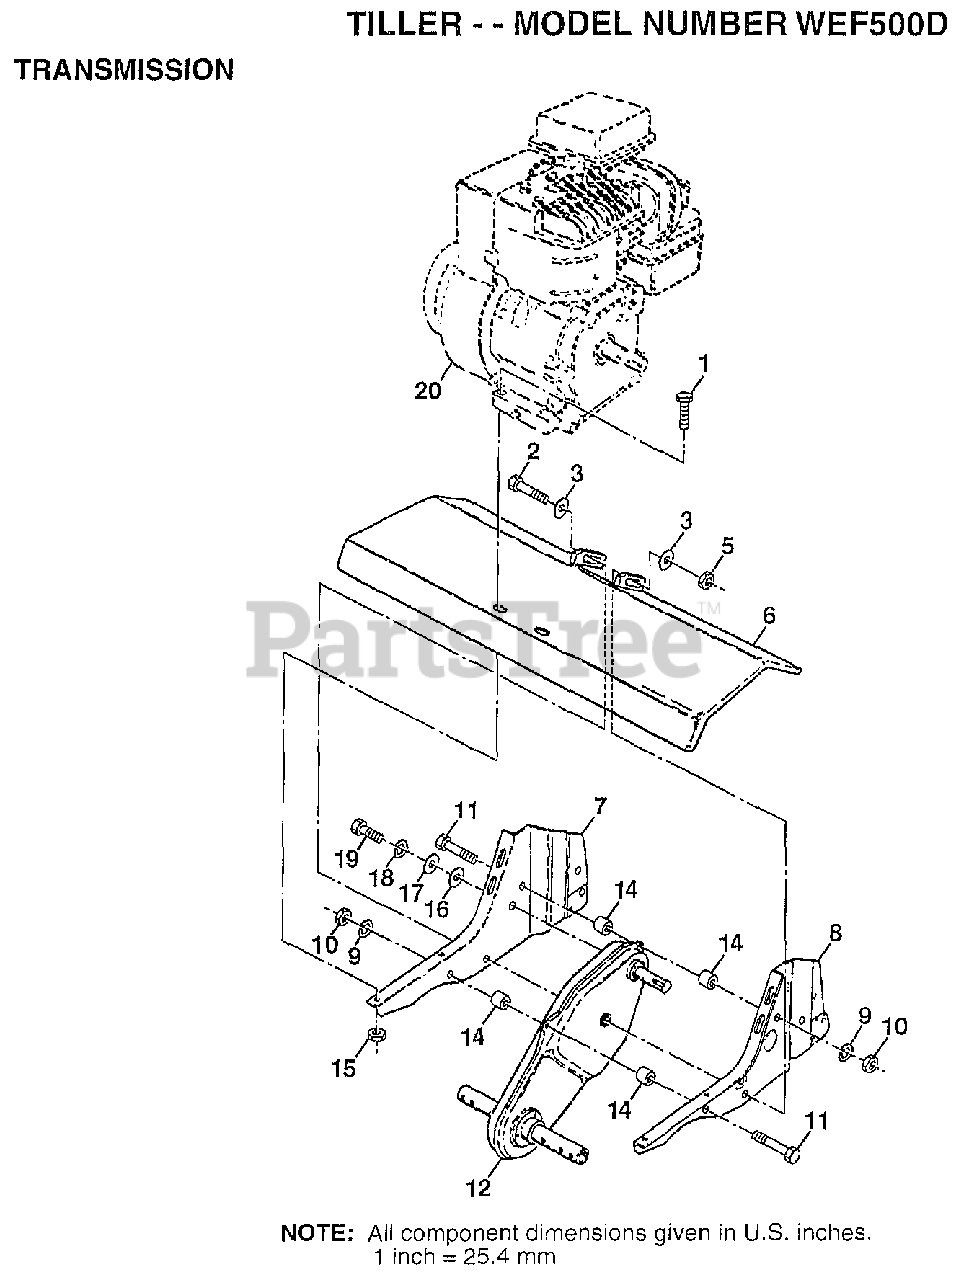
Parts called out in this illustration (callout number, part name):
1	BOLT
2	LOCKWASHER
3	WASHER
4	WASHER
6	BRACKET.ENGINE.RH
7	SPLIT SPACER RT
8	BRACKET.ENGINE.LH
9	LOCKWASHER
10	NUT.HEX.5/16-18
11	WASHER
13	NUT
16	BOLT HEX 3/8-16
17	BOLT.HEX.5/16-1.5
